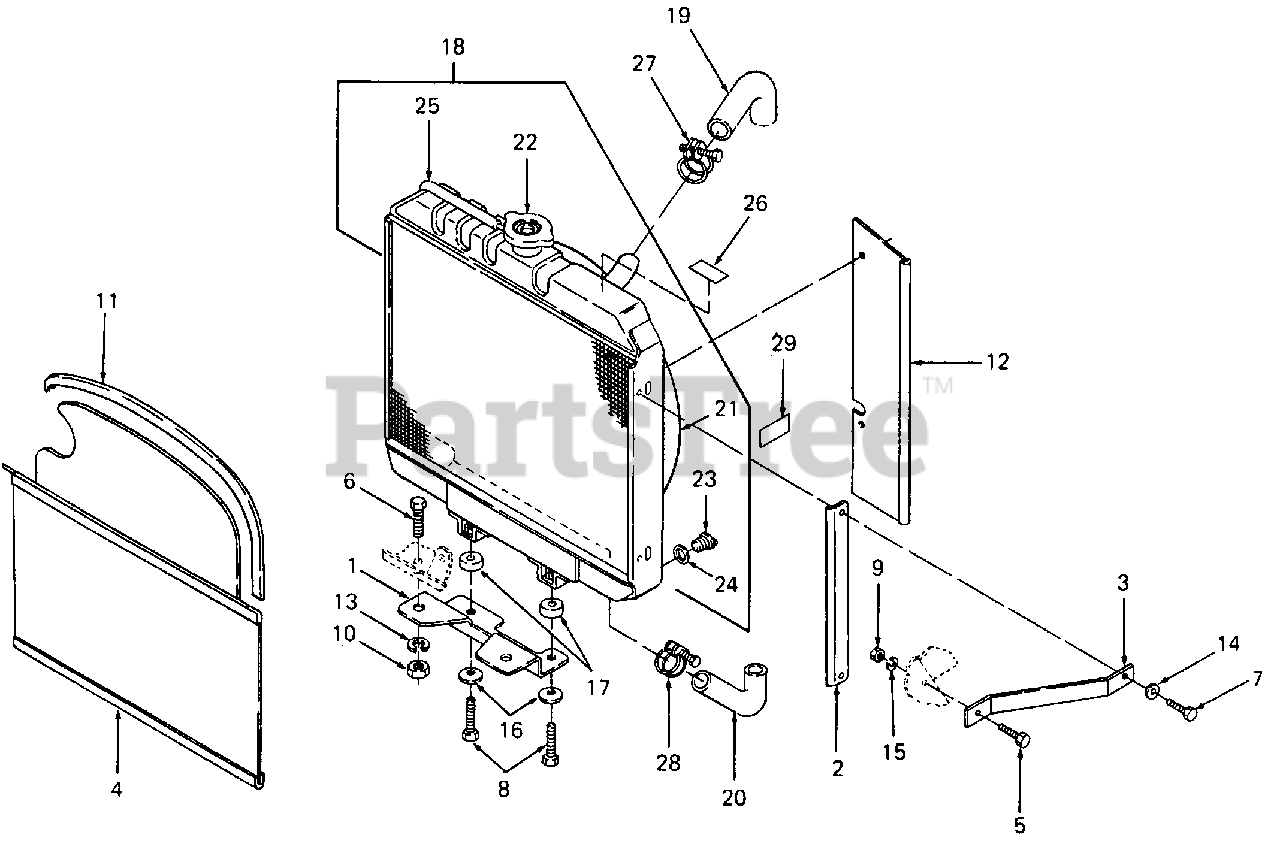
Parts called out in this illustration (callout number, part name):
1	Mount, Radiator
2	Track, Screen
3	Brace, Radiator
4	Heat Baffle Assy
5	Screw, Hex Cap, 1/4-20 X .62 Lg GR5
6	Screw, Hex Cap, 5/16-18 X .75 Lg GR5
7	Screw, Hex Cap, M6 X 14 mm Lg GR5
8	Screw, Hex Cap, M10 X 30 mm Lg GR8
9	Nut, Hex, 1/4-20 GR5
10	Nut, Hex, 5/16-18 GR5
11	Strip, Trim
12	Flap, Radiator Air
13	Washer, Lock, 5/16 Dia
14	Washer, Bell, .265 X .75 X .062
15	Washer, Lock, 1/4 Dia
16	Washer, Bell, .45 X 1.0 X .062
19	Radiator Hose, Upper
20	Radiator Hose, Lower
25	Pipe, Water Overflow
26	Label, Radiator
29	Label, Antifreeze
